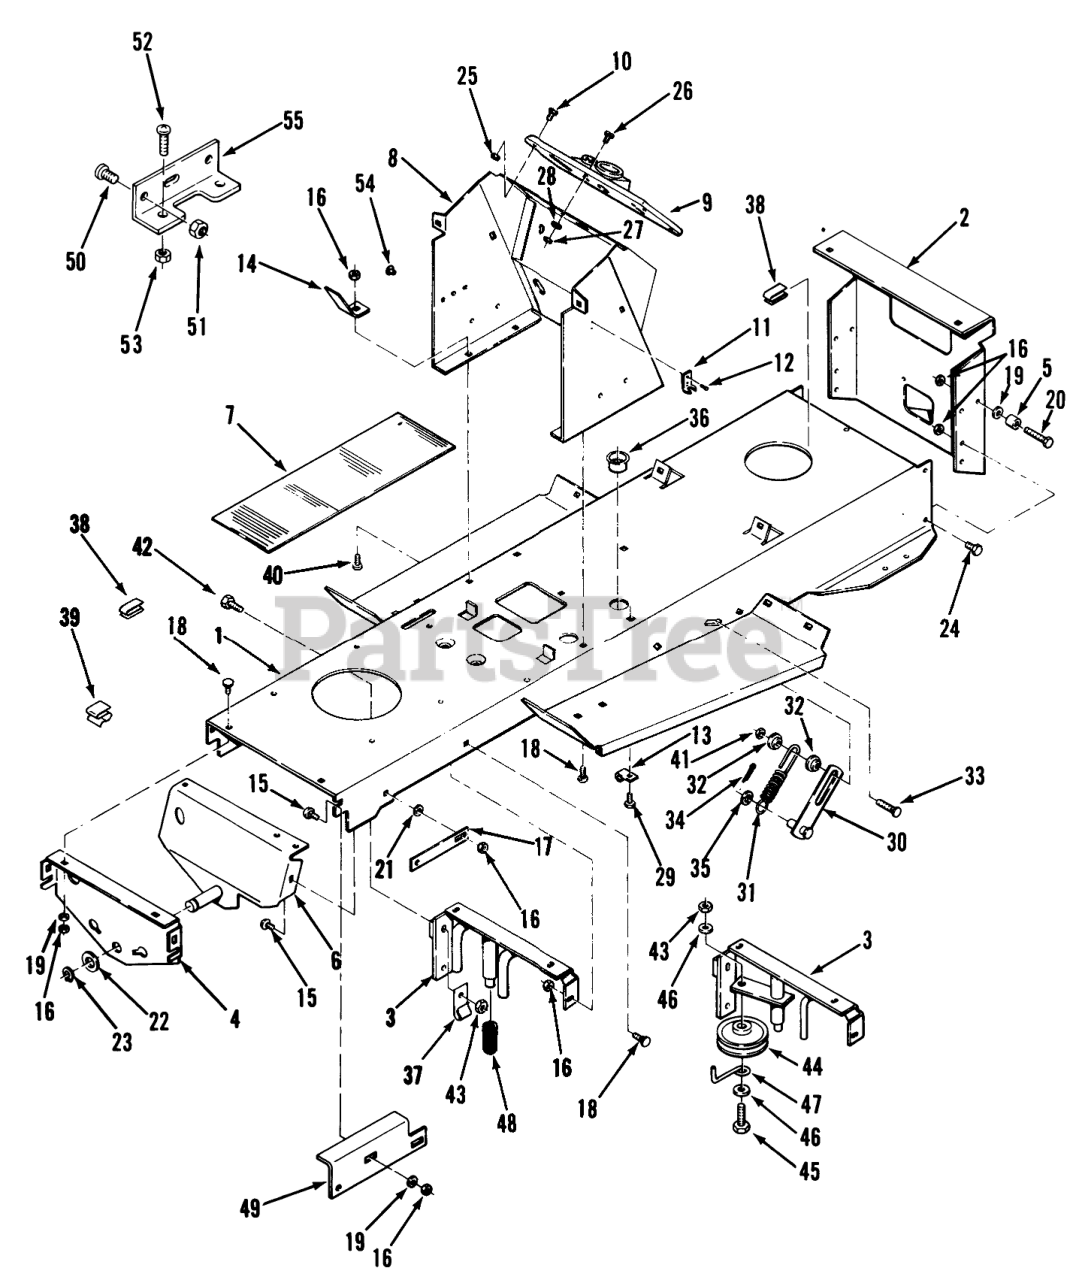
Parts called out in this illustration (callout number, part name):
1	Frame
2	PLATE-DRAWBAR R
3	ASS'Y-FRAME SUPPO R
4	PLATE SUPT - AXLE R
5	BEARING-CAM ROLLER
6	ASS'Y-AXLE SPT RE R
7	PAD-FOOTREST
8	Hoodstand 210-H, 210-5
9	CONSOLE
10	SCREW #10X.62 PHCR
11	Latch Keeper
12	RIVET
13	J-CLIP
14	BRACKET FUSE
15	Bolt-Carriage
16	Nut
17	STRAP R
18	Bolt
19	WASHER 5/16 SAE
20	Bolt
21	Washer-Lock
22	WASHER
23	Snap Ring
24	Bolt
25	Nut
26	Screw
27	Nut
28	Washer
29	Bolt
30	ASSY LINK B
31	SPRING
32	BUSHING
33	Bolt-Carriage
35	WASHER
36	BUSHING-NYLON 1.093
37	CLIP
38	RETAINER
39	CLIP-CABLE
40	Bolt
41	Nut
42	Bolt
43	NUT
44	IDLER PULLEY R
45	Bolt
46	Washer
47	RETAINER BELT R
49	BRACKET R.H. R
50	Screw
51	Nut
52	Screw
53	Nut
54	PLUG-NYLON .250
55	BRKT-FUSE HOLDER B
